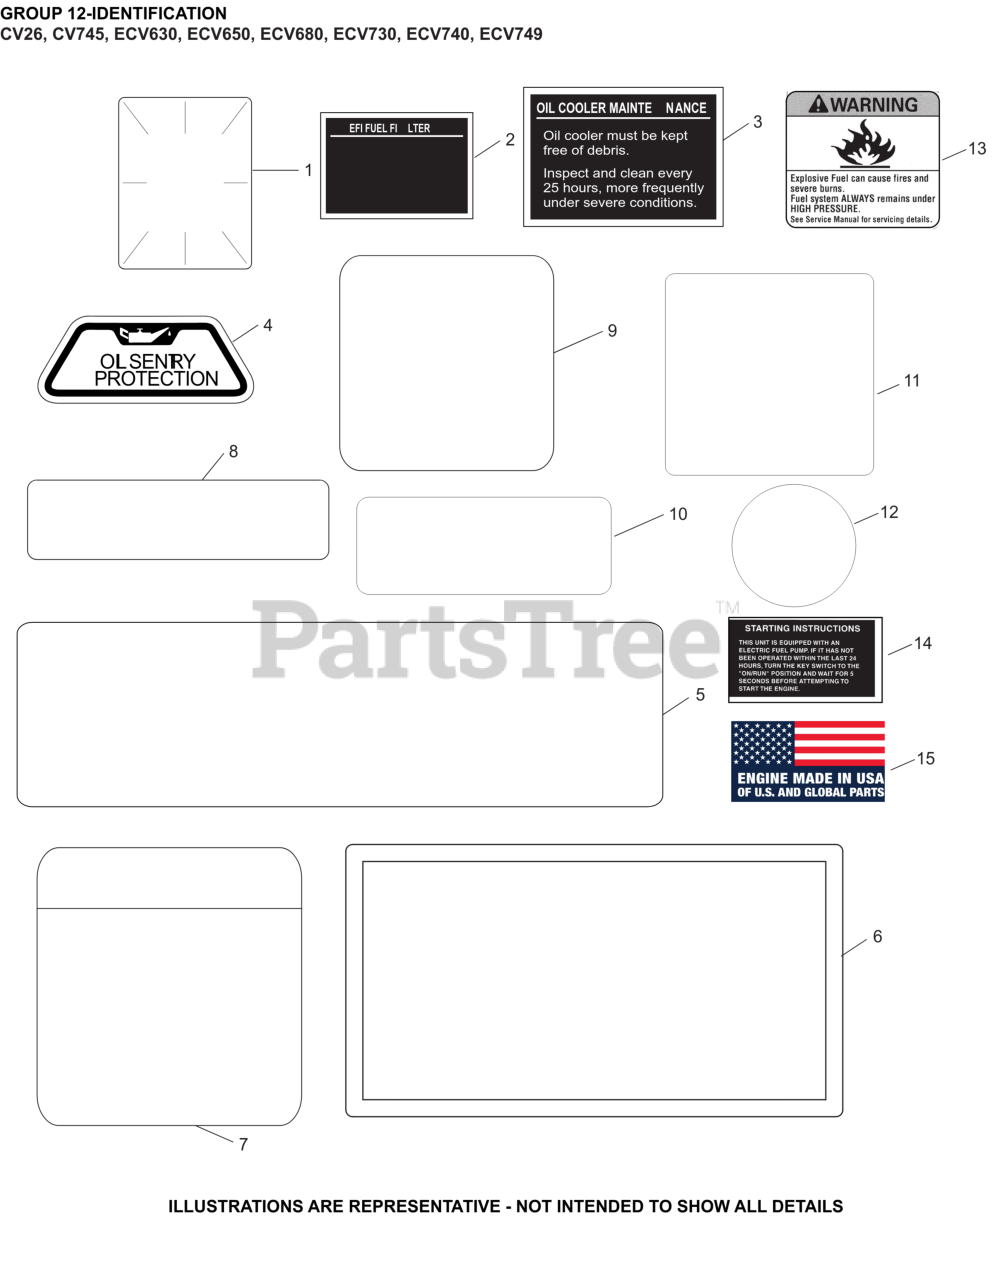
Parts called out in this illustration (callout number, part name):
1	LABEL, CLEAR LAMINATION
2	LABEL, EFI FUEL FILTER
9	DECAL HDAC, ECV749/747cc
15	DECAL, USA
16	LABEL, CANADIAN COMPLIANCE
